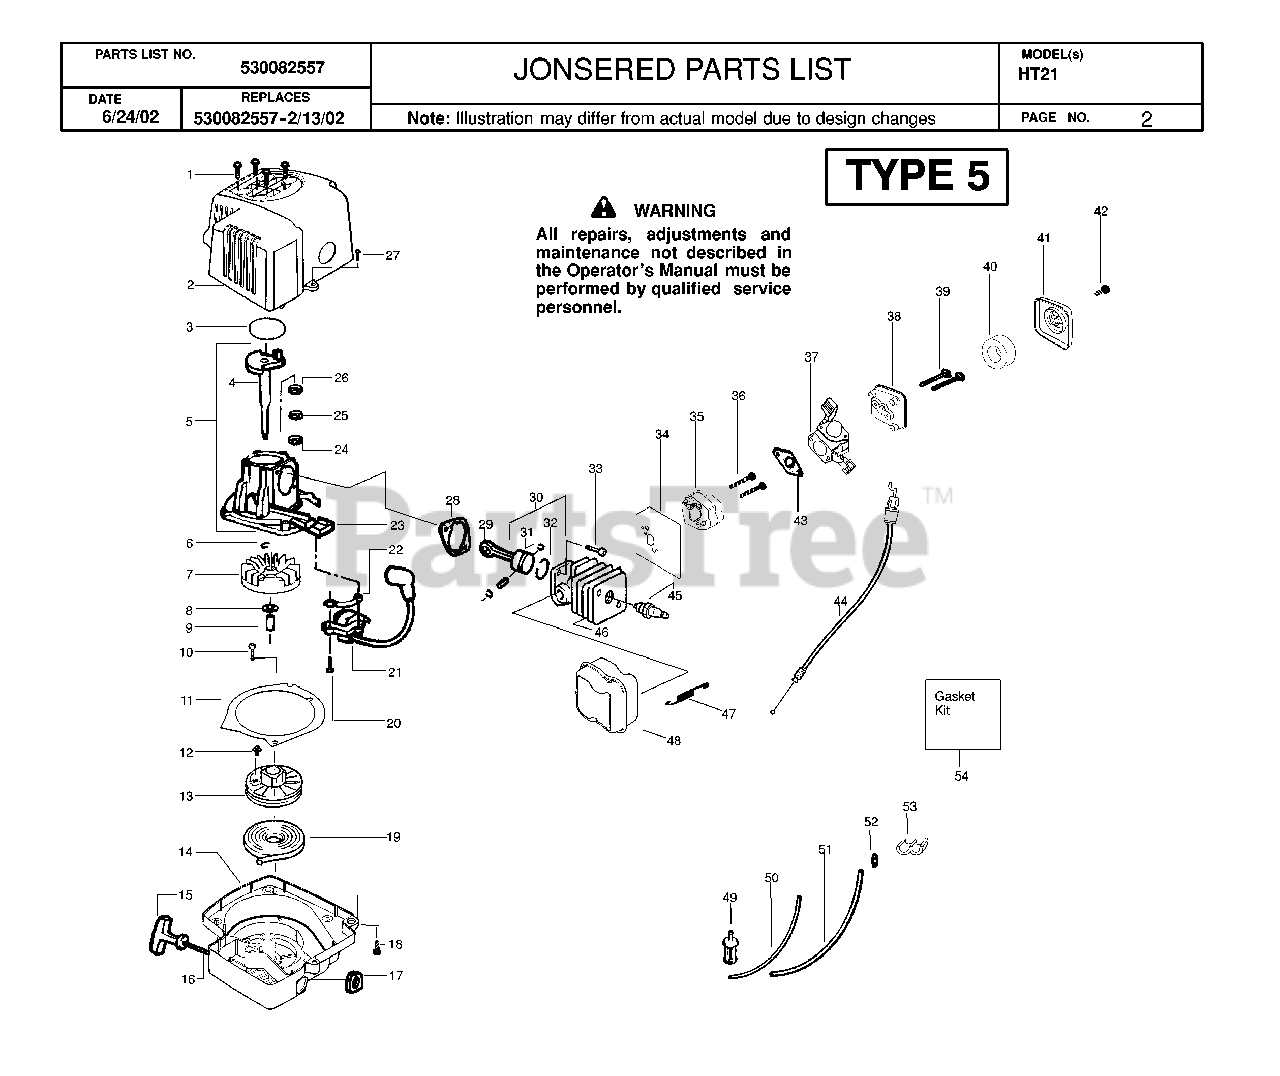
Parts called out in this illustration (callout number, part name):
1	SCREW
3	GASKET KIT
4	CRANKSHAFT
5	CRANK CASE/SHAFT ASSY.
6	RETAINING RING
7	FLYWHEEL
8	WASHER FLAT
10	SCREW-10-16 X 1/2 HI-LO
11	PLATE-BAFFLE
13	STARTER PULLEY
14	FAN HOUSING
15	HANDLE-STARTER
18	SCREW
19	STARTER SPRING
21	IGNITION MODULE
22	SPACER - IGNITION MODULE
23	CRANKCASE
24	OUTER BEARING
25	KIT-CRANKCASE SEAL
26	BEARING
28	GASKET KIT
30	PISTON
31	WRIST PIN RET.
32	PISTON RING
34	GASKET KIT
36	SCREW - CARB. ADAPTOR
37	CARBURETOR
41	AIR FILTER COVER
43	GASKET KIT
44	ASSY-THROTTLE CABLE
45	PLUG-SPARK (RCJ-6Y)
46	KIT-CYLINDER
48	KIT-SPARK MUFFLER
49	ASSY-PICK-UP
52	FUEL LINE FITTING
54	GASKET KIT
